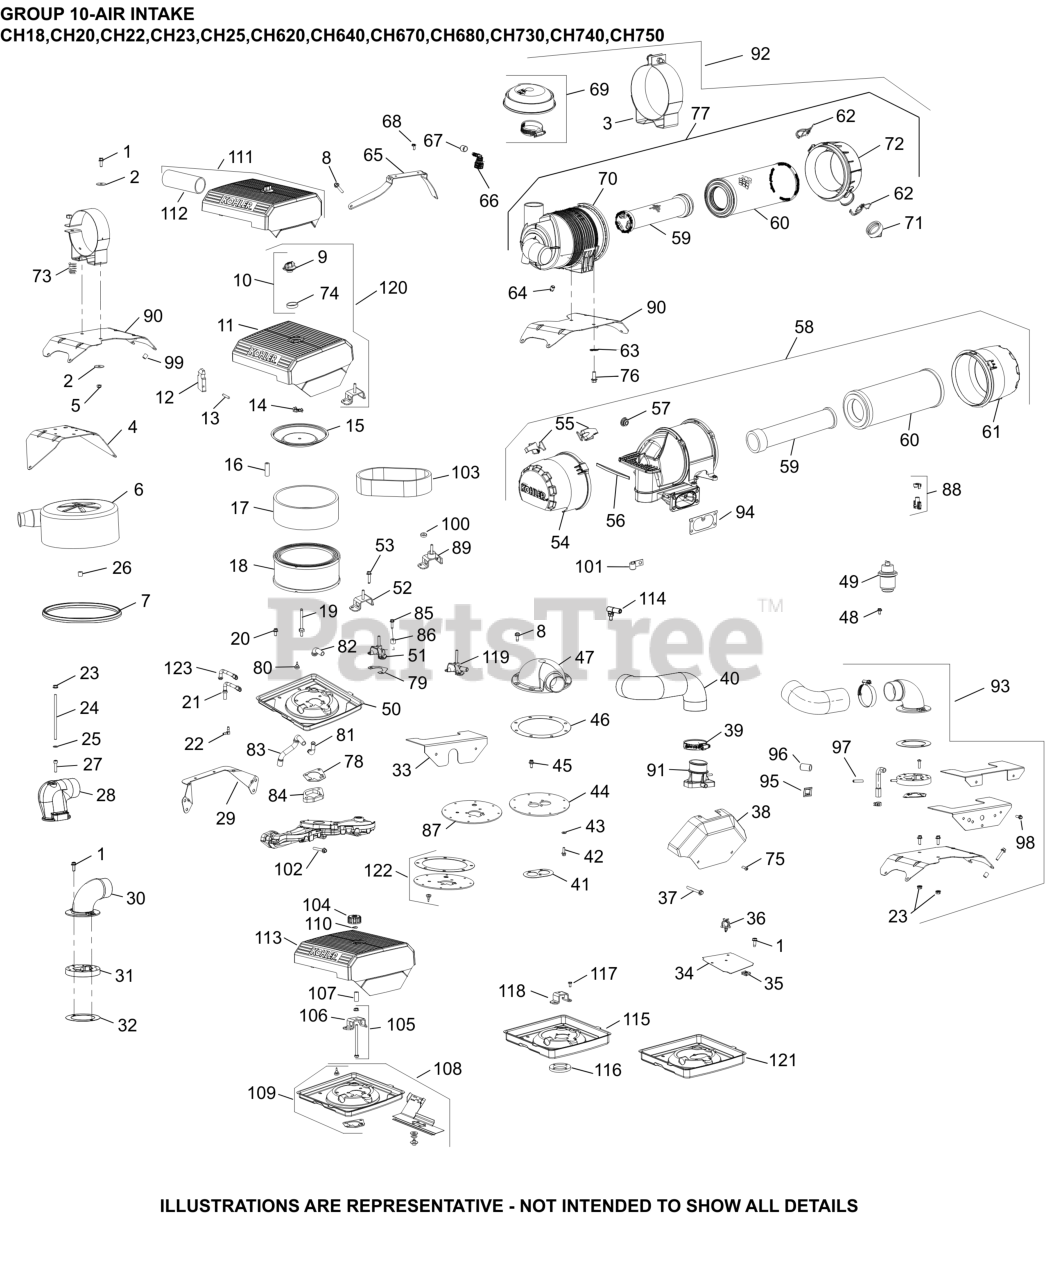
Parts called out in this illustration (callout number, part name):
9	KNOB, COVER
10	KIT, KNOB W/SEAL
11	COVER, AIR CLEANER
11	KIT, AIR CLEANER COVER
12	SEAL, INNER AIR CLEANER
14	NUT, WING
15	COVER, INNER AIR CLEANER
17	PRE CLEANER LOW ELEMENT
18	ELEMENT, AIR CLEANER
20	SCREW, FLG THD FRM M6X1.0X16
21	HOSE, EVAP
22	CONNECTOR, EVAPORATIVE HOSE
29	AIR CLEANER BRACKET
48	SCREW, THREAD FORMING
50	KIT, AIR CLEANER BASE
52	BRACKET, AIR CLEANER
78	GASKET, AIR CLEANER BASE
102	SCREW, FLG M6X1.0X40
120	KIT, AIR CLEANER COVER
NI	COVER, AIR CLEANER
